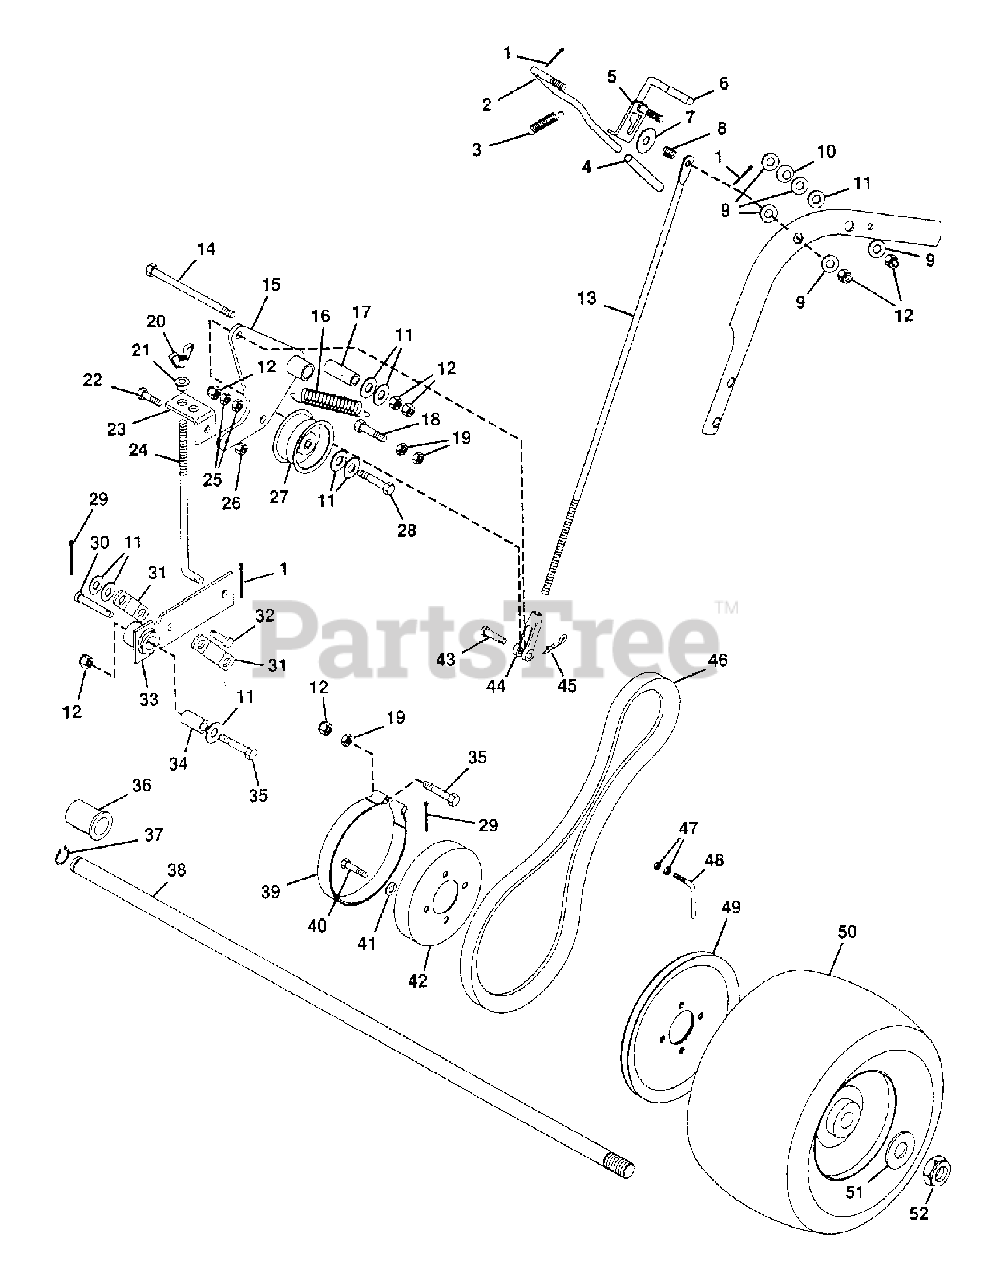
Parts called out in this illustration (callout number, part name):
1	PIN, COTTER .09X.75
2	LEVER, HAND CLUTCH
3	SPRING, EXTENSION
4	GRIP, HAND CLUTCH LEVER
5	WELDMENT, CLUTCH BRAKE
6	TIP, BRAKE LOCK LEVER
7	WASHER, FLAT .438X1.375X.083
8	SPRING, COMPRESSION
9	WASHER, NYLON .375X.75X.06
10	WASHER, SPRING .375 I.D.
11	WASHER, FLAT .406X.812X.065
12	NUT, LOCK 3/8-16
13	ROD, CLUTCH ACTUATING
14	BOLT, HEX 3/8-16X3.25
15	WELDMENT, WHEEL CLUTCH ARM
16	SPRING, CLUTCH IDLER
17	BUSHING, ST. .385X.610X1.80 STL.
18	BOLT, HEX 3/8-16X1.50
19	NUT, HEX 3/8-16
20	NUT, WING 5/16-18
21	BUSHING, FLANGE NYLON
22	BOLT, HEX 1/4-20X.750
23	BRACKET, BRAKE ROD
24	ROD, BRAKE
25	NUT, LOCK 3/8-16
26	NUT, LOCK 1/4-20
27	PULLEY, IDLER (PRO 32)
28	BOLT, HEX 3/8-16X2.00
29	PIN, COTTER .125X.75
30	PIN, CLEVIS 3/8X1.093
31	LINK, BRAKE ARM
32	PIN, CLEVIS 3/8X.594
33	WELDMENT, BRAKE ARM
34	BUSHING, ST. .391X.622X.950 STL.
35	BOLT, HEX 3/8-16X1.75
36	BUSHING, FLANGE
37	RING, RETAINING
38	SHAFT, AXLE (PRO 32)
39	ASSEMBLY, BRAKE BAND
40	BOLT, HEX 5/16-18X1.00
41	WASHER, LOCK 5/16 REG.
42	DRUM, BRAKE
43	PIN, CLEVIS .375X.948
44	CLEVIS, 3/8-24 ADJUSTABLE
45	PIN, COTTER HAIR
46	BELT-V, DRIVE WHEEL (PRO 32)
47	NUT, HEX 1/4-20
48	ROD, PULLEY CLEANING
49	SHEAVE, PRO 32 DRIVE WHEEL
50	ASSEMBLY, WHEEL 13X5.00-6
51	RACE, BEARING THRUST
52	NUT, LOCK 3/4-10 LIGHT THIN
